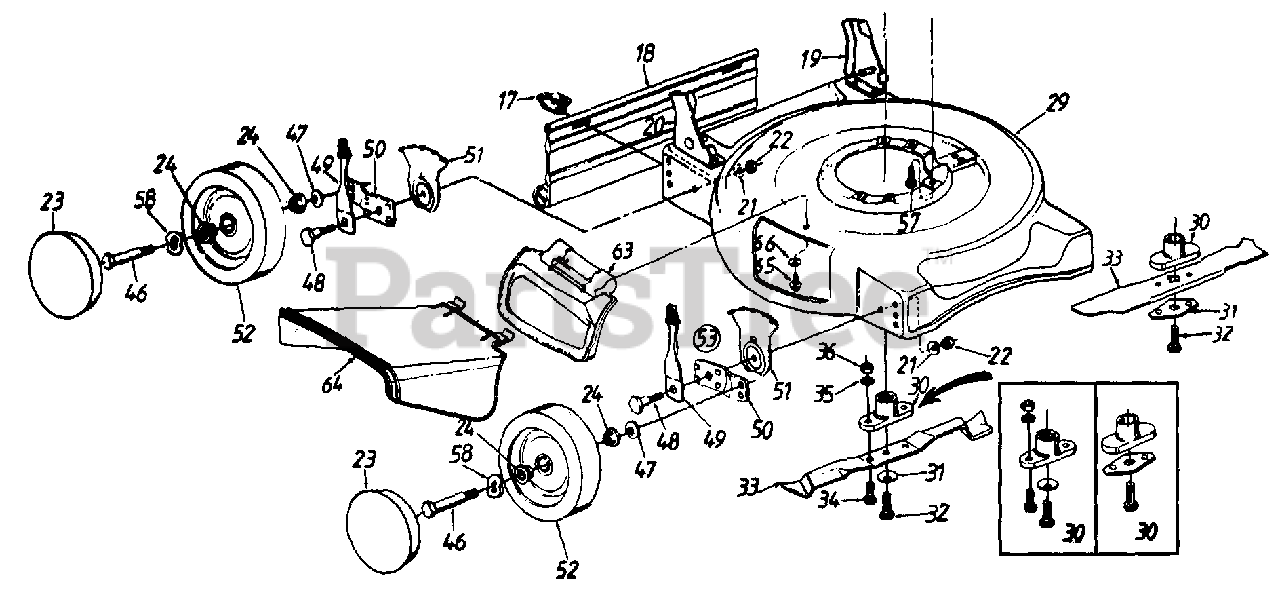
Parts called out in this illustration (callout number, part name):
17	Hinge Clip
18	Rear Flap
21	Bell-Wash. .39" I.D. x 1.38"
22	Hex Nut 3/8-16 Thd.
23	Hub Cap
24	Bearing
29	20" Deck Assy.
30	Blade Adapter Kit
31	Bell-Wash. .46" I.D.
32	Hex Bolt 7/16-20 x 1.5" Lg.
33	20" Mulch Blade
34	Hex Bolt 3/8-24 x 1" Lg.
35	L-Wash. 3/8" I.D.
36	Hex Nut 3/8-24 Thd.
47	Bell-Wash. .400" I.D. x .88"
48	Shld. Bolt .50" Dia. x .357"
49	Spring Lever Assy. w/Knob
51	Height Adj. Plate
52	Wheel Assy. Comp.
53	Ht Adj. Assy. Comp. R.F. & L.R.
57	Hex L-Wash. Hd. Scr. 3/8-16 x 1.0" Lg.
58	Wave Washer .51" I.D.
63	Mulching Plug
64	Chute Deflector
65	Bell-Wash. 1/4" I.D.
66	Hex Wash. Hd. TT-Tap Scr. 1/4-20 x .5" Lg.
